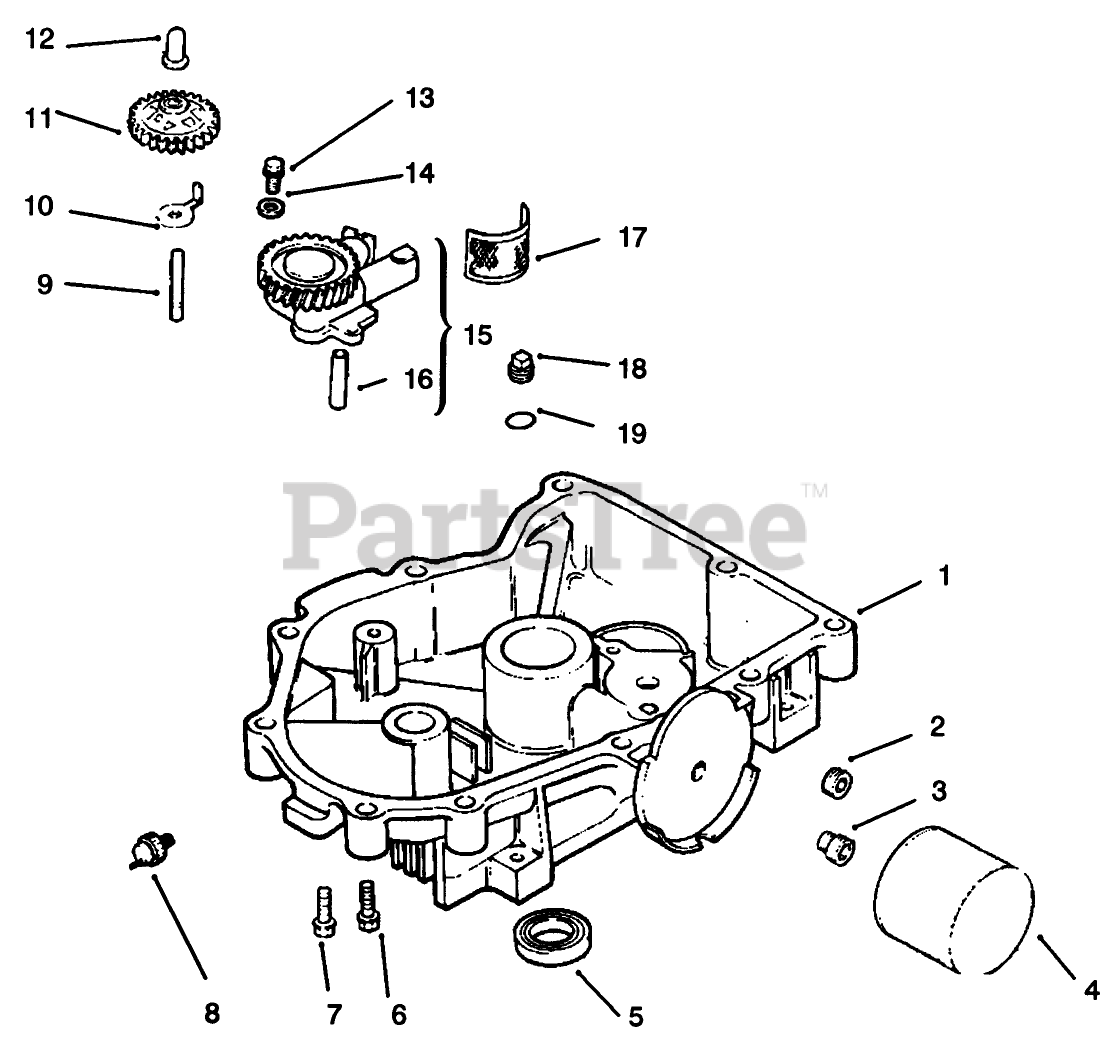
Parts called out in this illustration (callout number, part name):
1	Oil Pan
2	Plug-HS 3/8 NPTF (Only On: 72103, 72083)
3	Nipple-Oil Filter
4	Filter-Oil
5	Seal-Oil
6	Screw M8x1.25x45 (Only On: 72103, 72083)
8	Switch-Oil Pressure
9	Shaft-Govenor Gear
10	Tab-Locking
11	Kit-Governor Gear Assembly (Incl. Ref. #7)
12	Pin-Governor
13	Screw-Valve Cover
14	Washer-Governor
15	Oil Pump ASM INC 16
16	Tube-Oil Pickup (Only On: 72103, 72083)
17	Screen-Oil Pickup
